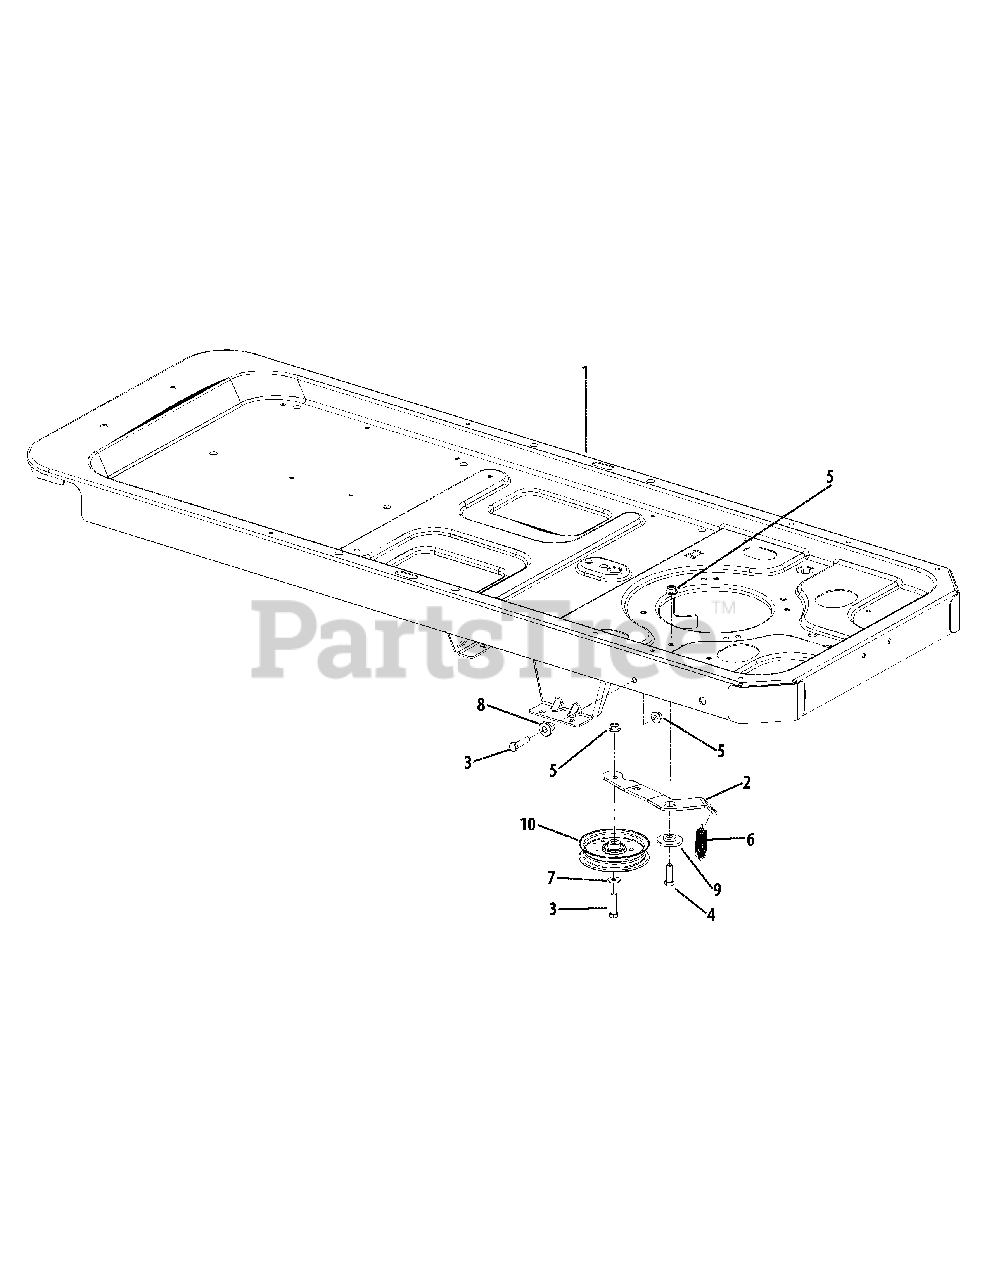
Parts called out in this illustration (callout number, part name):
1	Frame Assembly
3	Hex Screw, 3/8-16 x 1.5
4	Hex Screw, 3/8 -16 x 1.25
5	Flange Nut, 3/8 -16
6	Extension Spring, .75 x 5.06
7	Flat Washer, .408 x .875 x .059
8	Shoulder Spacer, .39 x 1.0 x .7
9	Shoulder Spacer, .884 x .19
10	Idler Pulley, 4.25 Dia.
